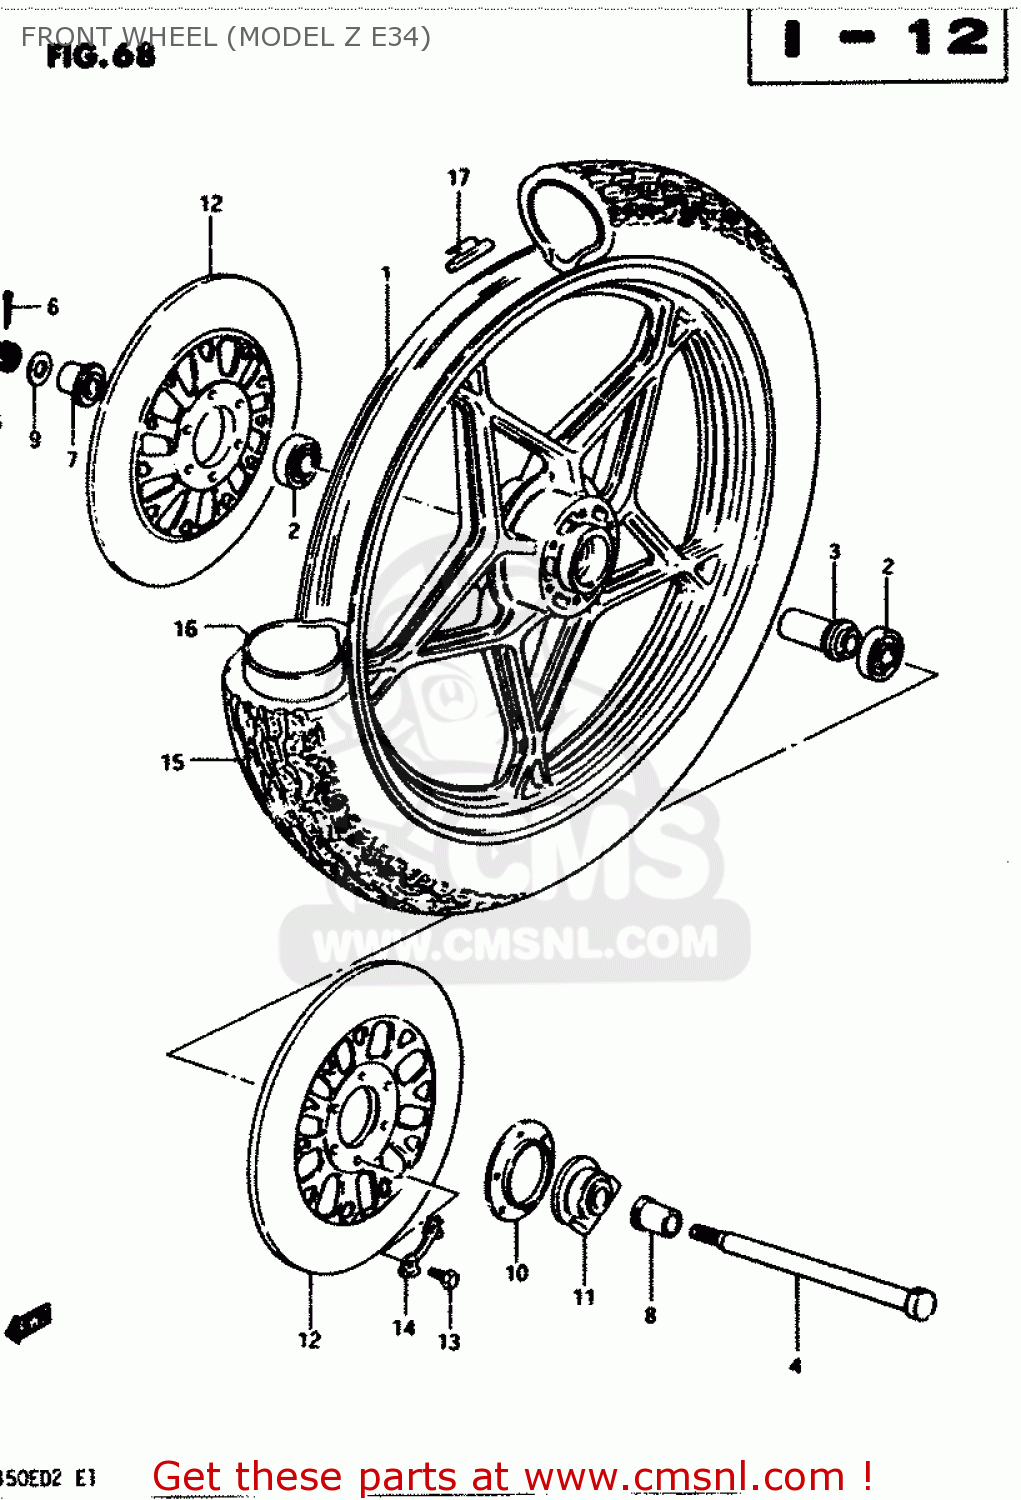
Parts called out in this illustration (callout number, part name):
1	WHEEL, FRONT (1.85-18)
2	BEARING
3	SPACER,FR HUB BEARING
4	AXLE,FRONT
5	NUT 12MM
6	COTTER PIN
7	SPACER,FR HUB BEARING,R
8	SPACER(15X22X30)
9	WASHER
10	DUST SEAL,SPEEDOMETER GEAR BOX
11	BOX ASSY,SPEEDOMETER GEAR
12	DISK, FRONT BRAKE
13	BOLT(8X25)
14	WASHER
15	TIRE,FRONT
16	TUBE,INNER
17	BALANCER,WHEEL
